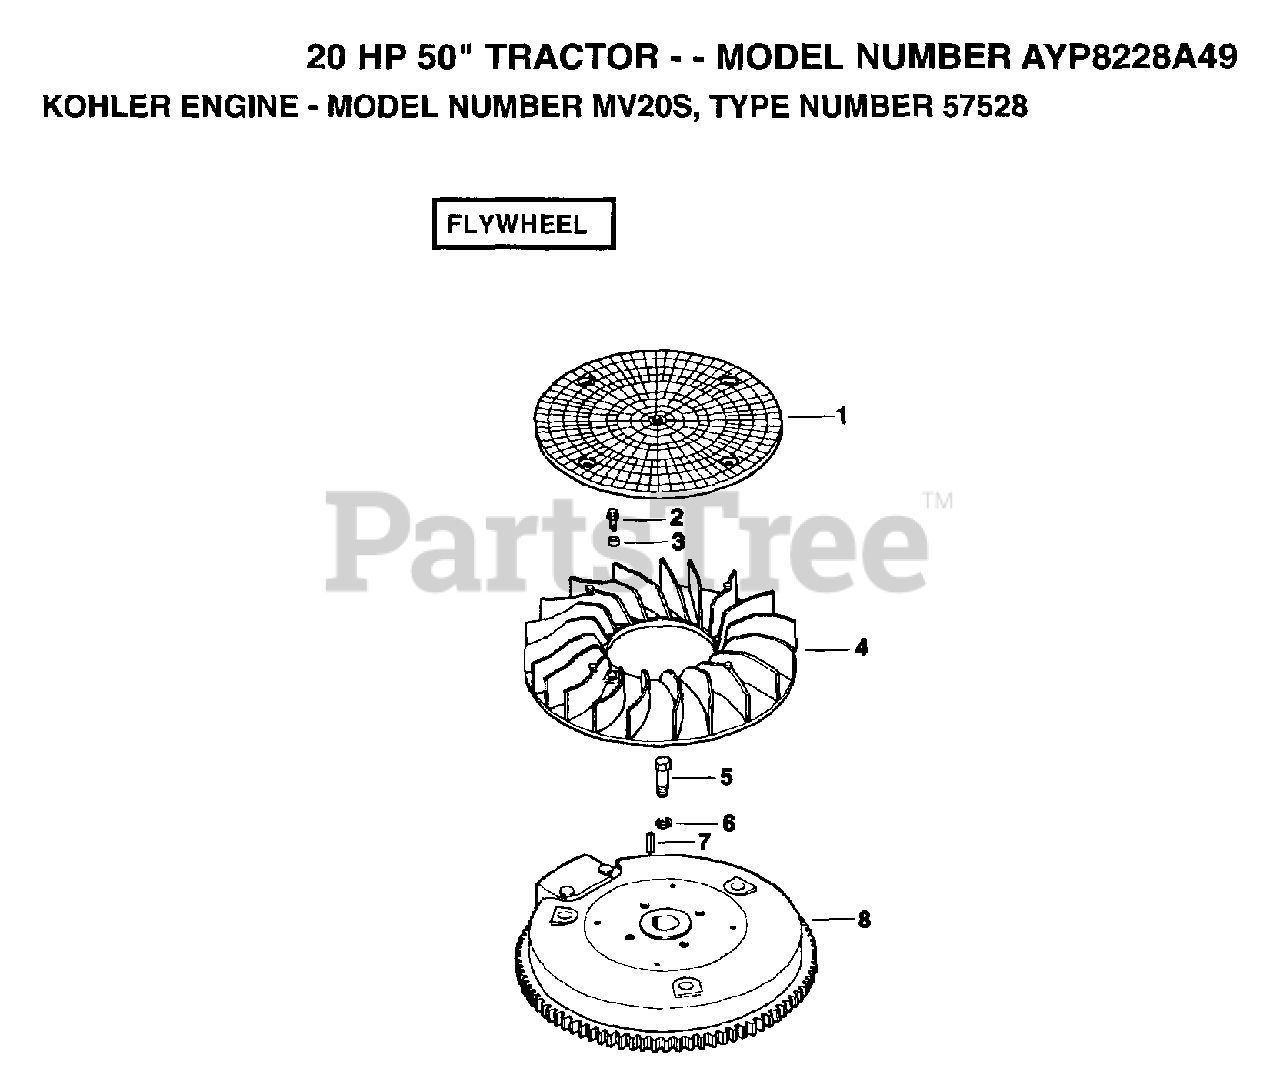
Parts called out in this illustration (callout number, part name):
2	SCREW, HEX 1/4-20 X 5/8
5	SCREW, 3/8-24X1-1/4
7	KEY
